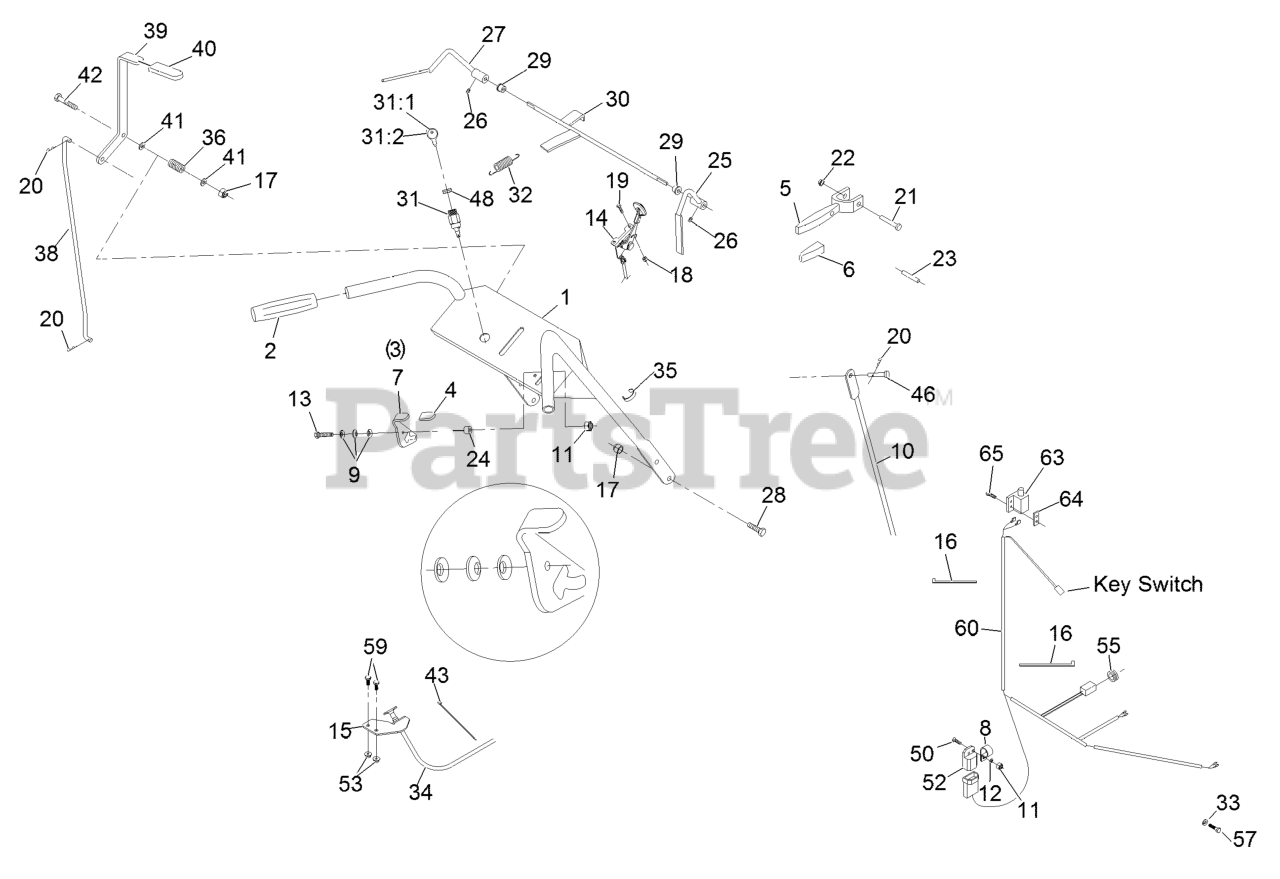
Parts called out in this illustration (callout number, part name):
1	KIT,HANDLE W/DECALS METRO
4	GRIP-LATCH
5	DRIVE LEVER ASM
6	GRIP-LEVER, DRIVE
8	CLIP-LOOM
9	WASHER-SPRING
10	LINKAGE-WHEEL, DRIVE
11	NUT-LOCK, NI
12	WASHER-FLAT
13	SCREW-HH
14	CONTROL, THROTTLE
15	BRACKET-CABLE, CHOKE
16	TIE-CABLE
17	NUT-LOCK, NI
18	NUT-LOCK, NI
19	BOLT-CARR
20	PIN-COTTER
21	PIN-LEVER, DRIVE
22	NUT-PUSH
23	PIN-ROLL
25	LEVER-RH
26	SCREW-SET
27	LEVER-LH
28	SCREW-HH
29	BUSHING-NYLON
30	WLD,ROD OPC
31	SWITCH & KEY (INCLUDES NU
31:1	KEYS-IGNITION (SPARE PAIR
31:2	KEY-IGNITION
32	SPRING-EXTENSION
33	WASHER-PLAIN
34	CABLE-CHOKE
35	CLIP-CABLE
36	SPRING-COMPRESSION
38	LINKAGE-BLADE, UPPER
39	LEVER ASM
40	GRIP-LEVER
41	WASHER-FLAT
42	SCREW-HH
43	TIE-PLASTIC
46	PIN-CLEVIS
48	NUT-SWITCH, IGNITION
50	SCREW-HH
52	MODULE-INTERLOCK
55	GROMMET
57	SCREW-HH
59	SCREW-HH
60	HARNESS-WIRE
63	SWITCH-OPEN, NORMALLY
64	PLATE-TAPPED
65	SCREW-PPH
